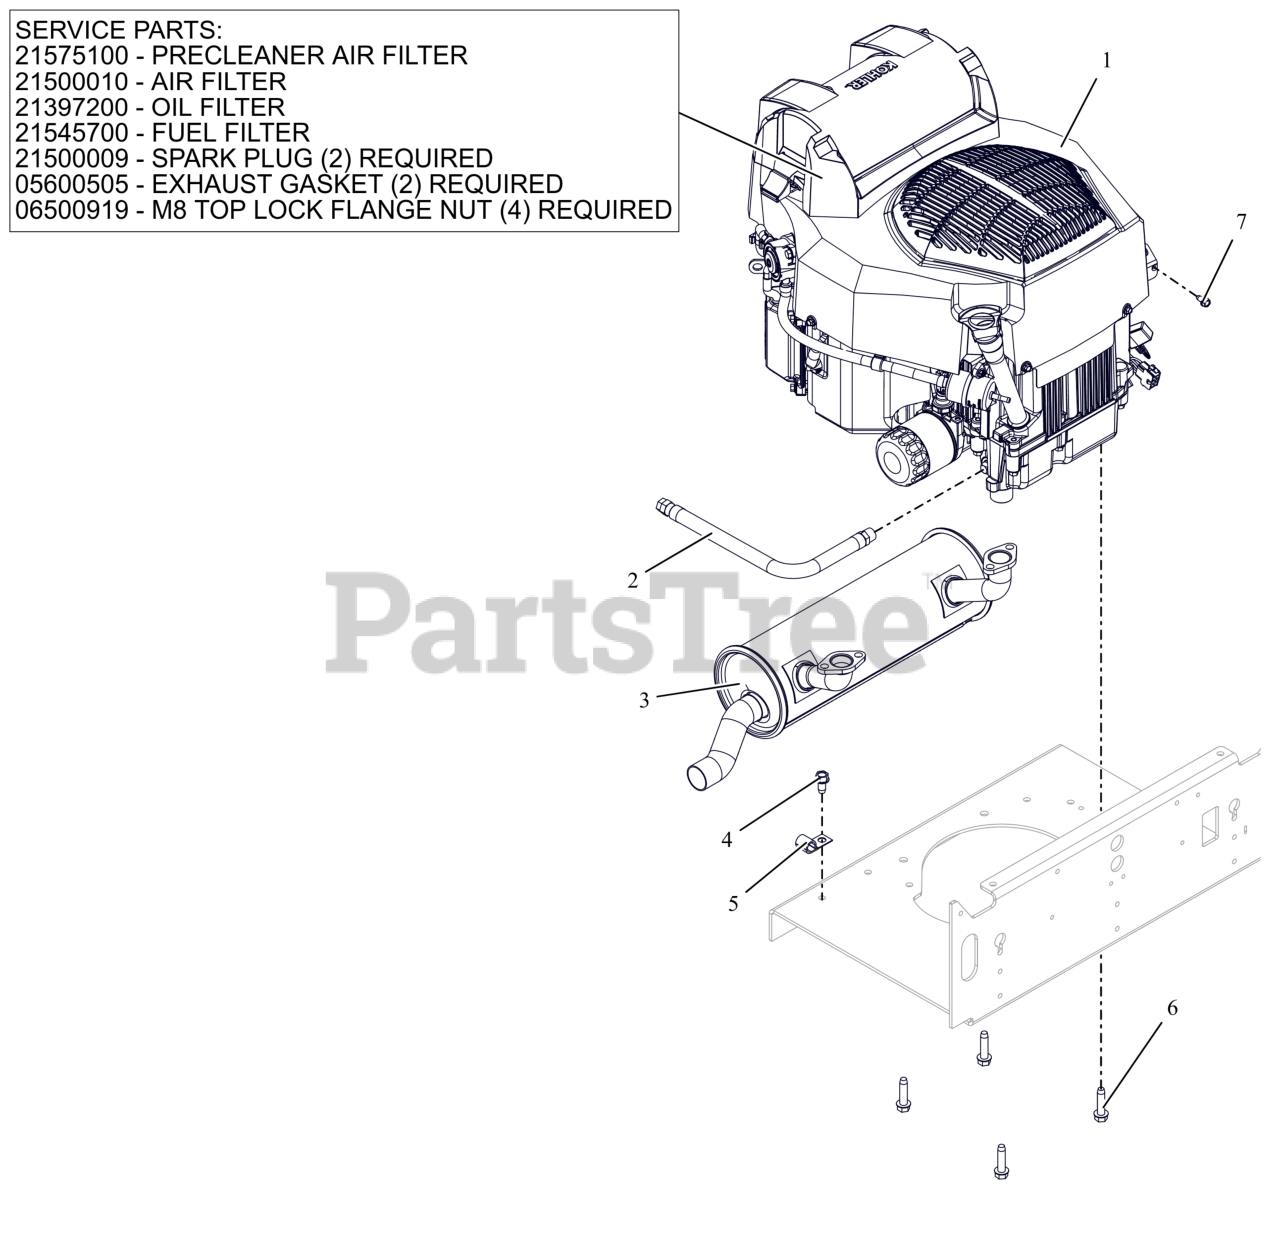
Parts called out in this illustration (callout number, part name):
1	ENGINE, KOHLER ZT740 CONFIDANT
1	PRECLEANER AIR FILTER
1	AIR CLEANER, KOHLER CONFIDANT
1	FILTER, OIL - KOH CV20
1	FILTER-FUEL KOHLER COURAGE PRO
1	PLUG, SPARK KOHLER
1	GASKET, MUFFLER KOHLER TWIN
1	NUT-LK-TOP-FLG M8 ZCC
2	HOSE, OIL DRAIN
3	MUFFLER, ZT730/ZT740
4	SCR,TAP .375-16X.75 HWH TR ZCC
6	SCR-TAP .38-16X1.50 HWH ZCC
7	SCR-TAP .25-20X.50 HWH ZCC
